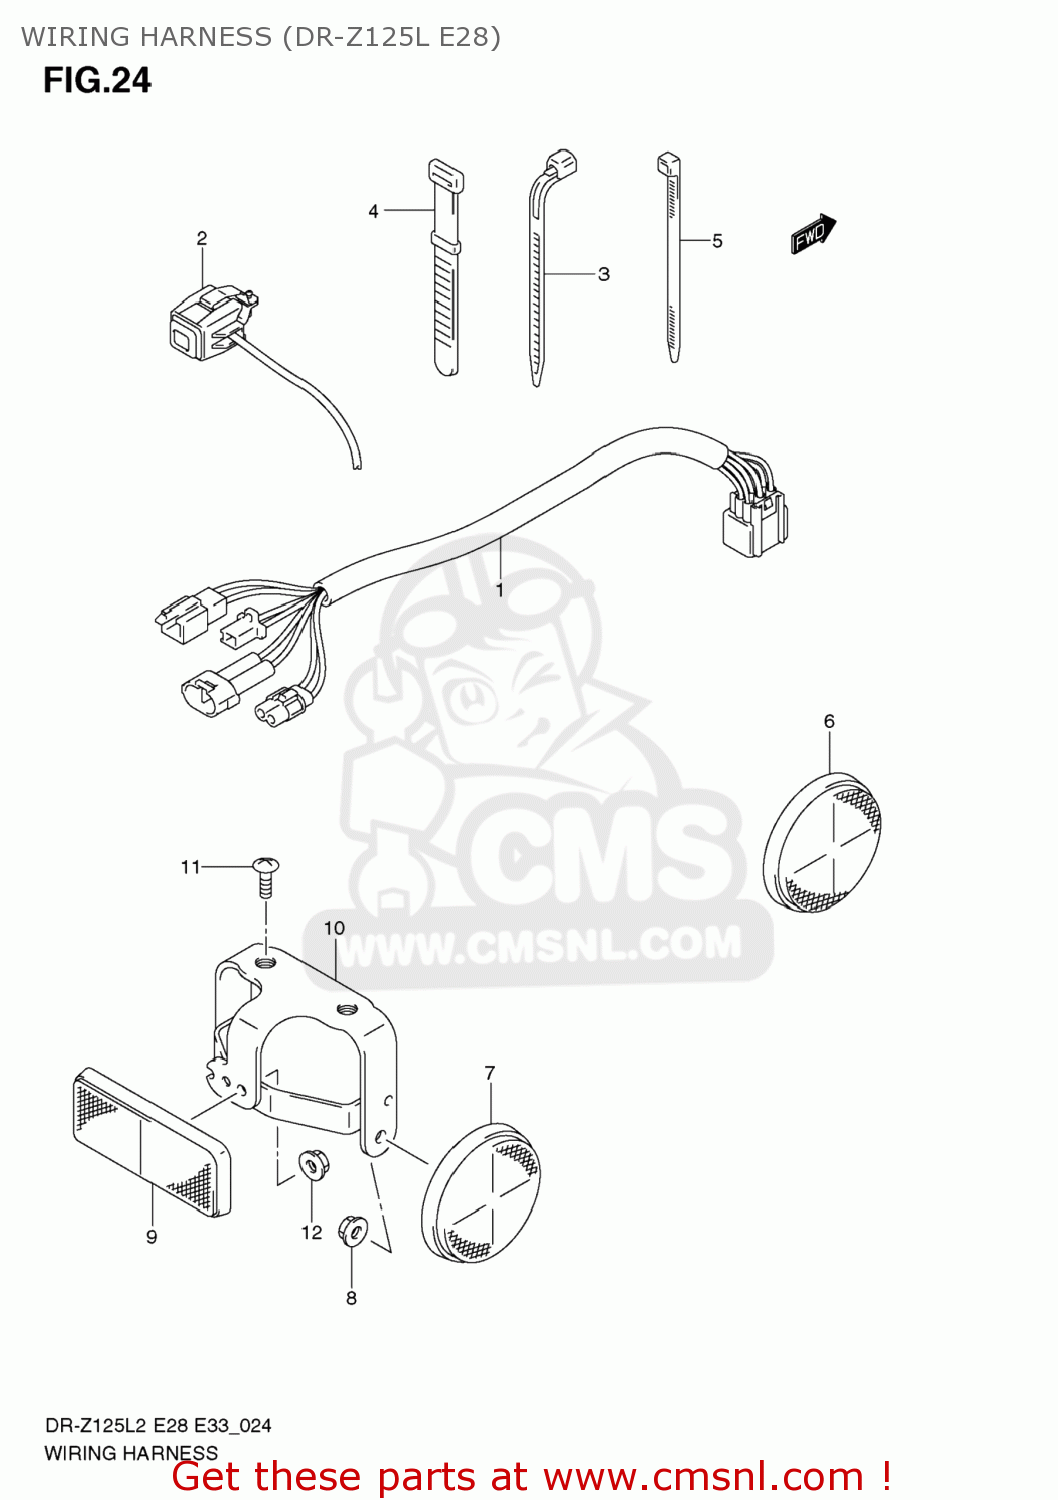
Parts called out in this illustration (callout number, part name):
1	HARNESS,WIRING
2	SWITCH ASSY,ENGINE STOP
3	CLAMP(L:165)
4	CLAMP(L:120)
5	CLAMP(L:145)
6	REFLEX REFLECTOR ASSY,FR SIDE
7	REFLEX REFLECTOR,RR
8	NUT
9	REFLECTOR ASSY,RR
10	BRACKET,SIDE & RR REFL
11	SCREW
12	NUT
